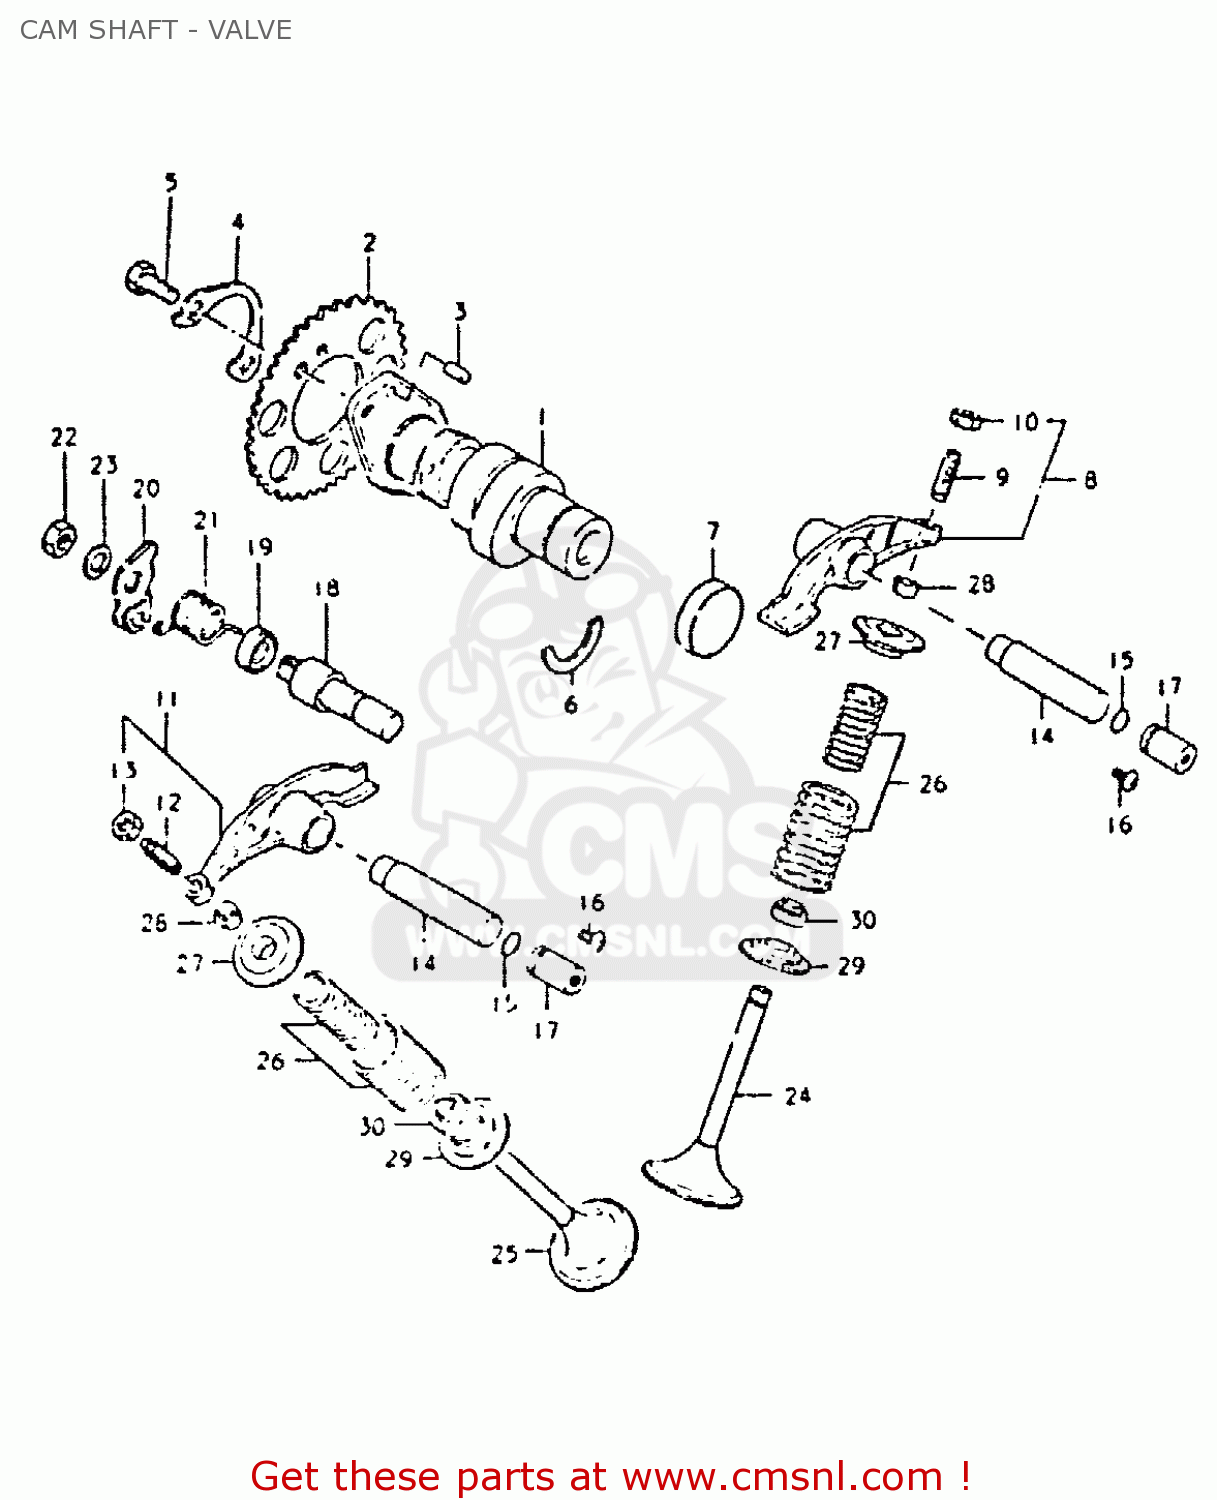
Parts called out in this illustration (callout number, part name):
1	CAMSHAFT
2	SPROCKET,CAMSHAFT
3	PIN
4	WASHER,CAM CHAIN SPROCKET
5	BOLT(6X12.5)
6	C RING
7	PLUG
8	ARM,VALVE ROCKER
9	SCREW,TAPPET ADJUSTING
10	NUT,ADJUSTING SCREW
11	ARM,VALVE ROCKER
12	SCREW,TAPPET ADJUSTING
13	NUT,ADJUSTING SCREW
14	SHAFT,VALVE ROCKER
15	O-RING
16	SCREW
17	CAP,ROCKER ARM SHAFT
18	SHAFT,DECOMPRESSION
19	OIL SEAL
20	LEVER,DECOMPRESSION SHAFT
21	SPRING
22	NUT 8MM
23	WASHER
24	VALVE,INTAKE
25	VALVE,EXHAUST
26	SHIM,TAPPET
27	RETAINER,VALVE SPRING
28	COTTER VALVE
29	SEAT,VALVE SPRING
30	SEAL,OIL(7X14.4X9)
